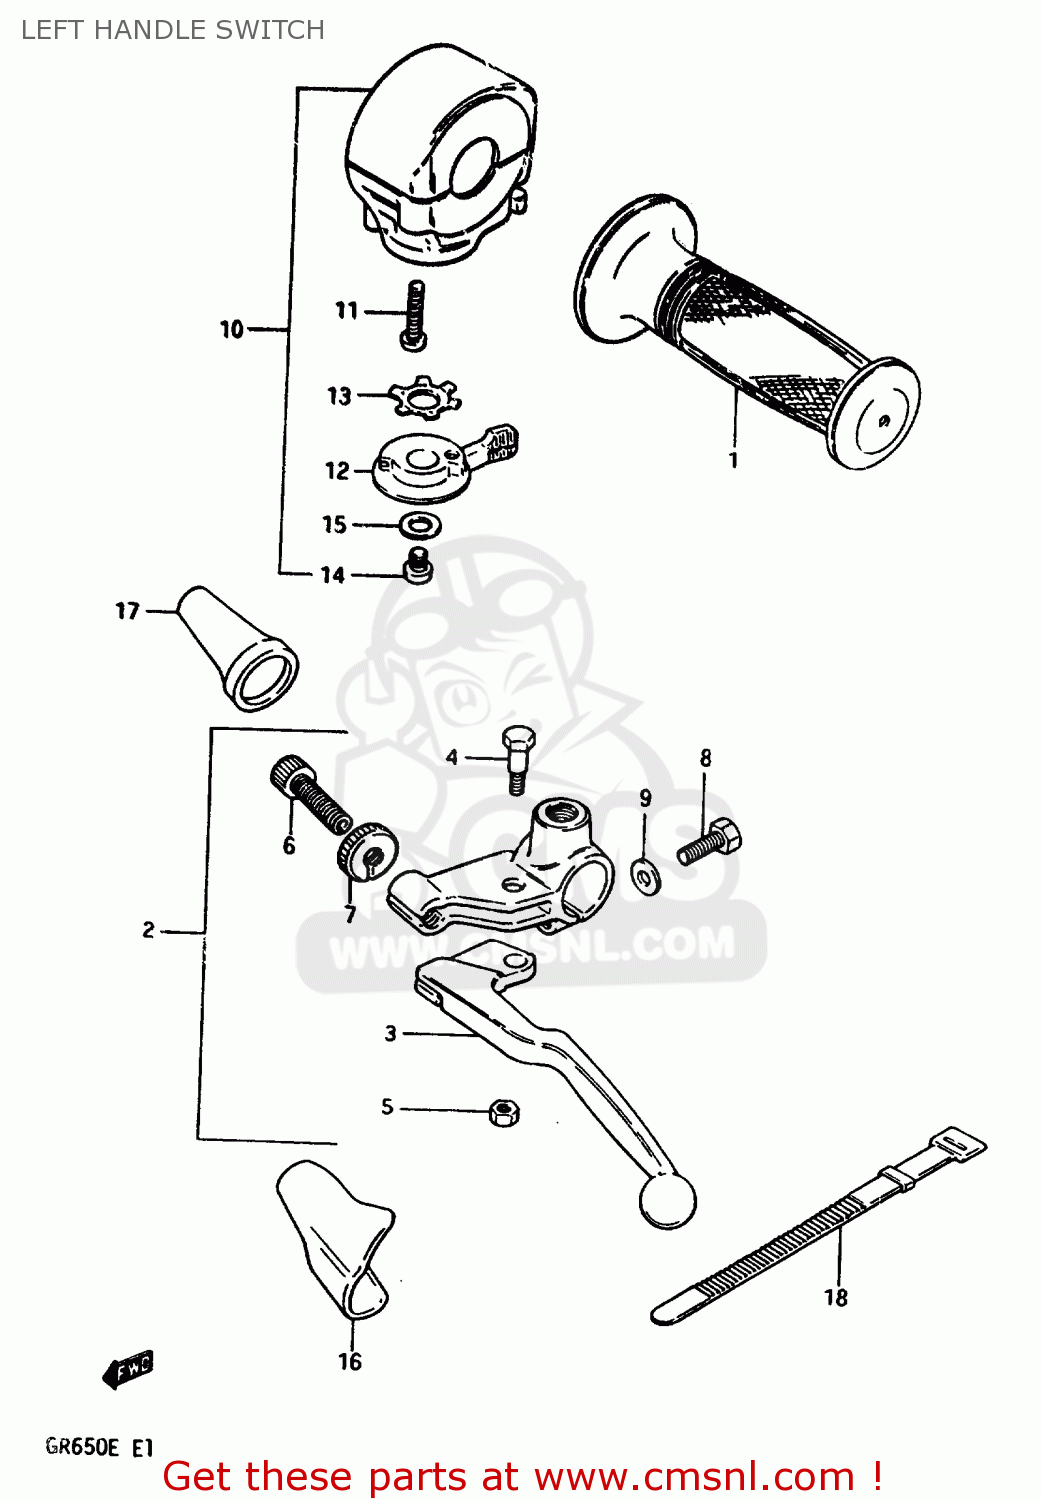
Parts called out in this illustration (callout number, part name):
1	GRIP
2	LEVER ASSEMBLY,CLUTCH
3	LEVER,CLUTCH
4	BOLT,LEVER PIVOT
5	NUT 6MM
6	ADJUSTER,CABLE
7	NUT,CABLE ADJUSTER LOCK
8	BOLT,CLUTCH LEVER HOLDER
9	WASHER
10	SWITCH ASSY,HA
11	SCREW
12	LEVER,STARTER
13	WASHER
14	SCREW
15	WASHER 6MM
16	COVER,CLUTCH LEVER
17	BOOT,CLUTCH CABLE
18	CLAMP(L:120)
